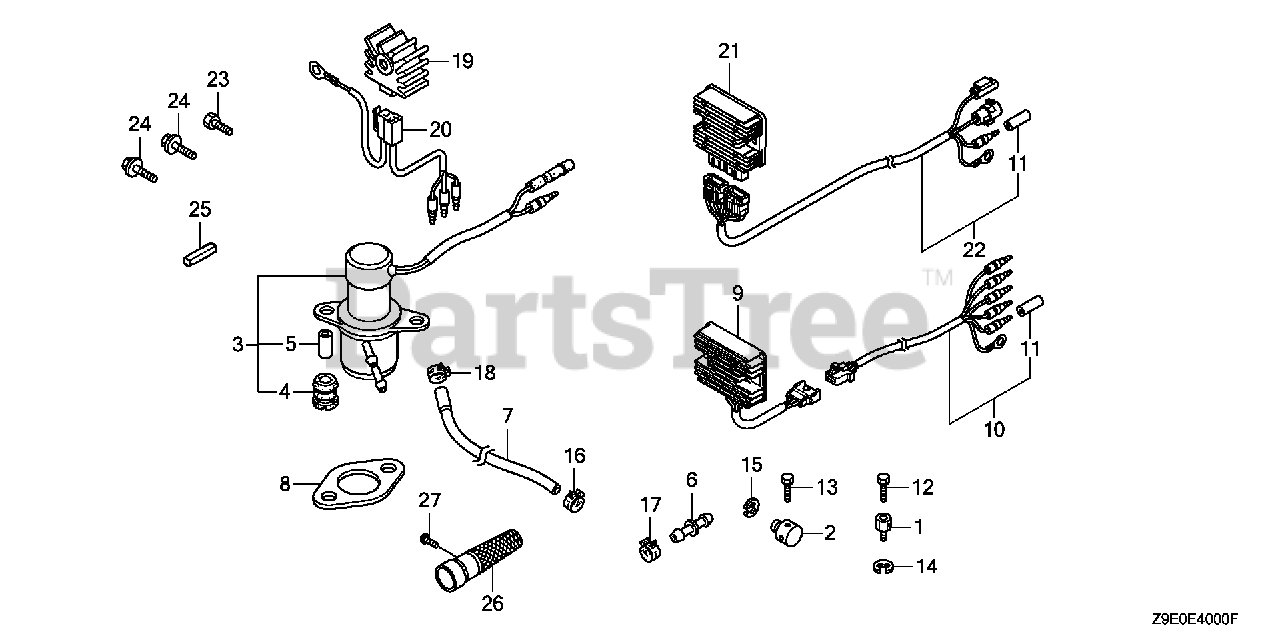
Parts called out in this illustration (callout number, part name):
3	PUMP ASSY., FUEL (MSDS)
4	RUBBER, FUEL PUMP MOUNTING
5	COLLAR, FUEL PUMP DISTANCE
6	JOINT, FUEL TUBE
7	TUBE, FUEL SPECIAL (FKM)
8	GASKET, EX. PIPE
9	RECTIFIER ASSY., REGULATOR (20A)
10	SUB-WIRE HARNESS ASSY.
11	PLUG, CONNECTOR (OUTER)
16	CLAMP, TUBE (D8)
17	CLAMP, TUBE (D8.5)
18	CLAMP, TUBE (D8.5)
25	KEY (6.3X6.3X43)
